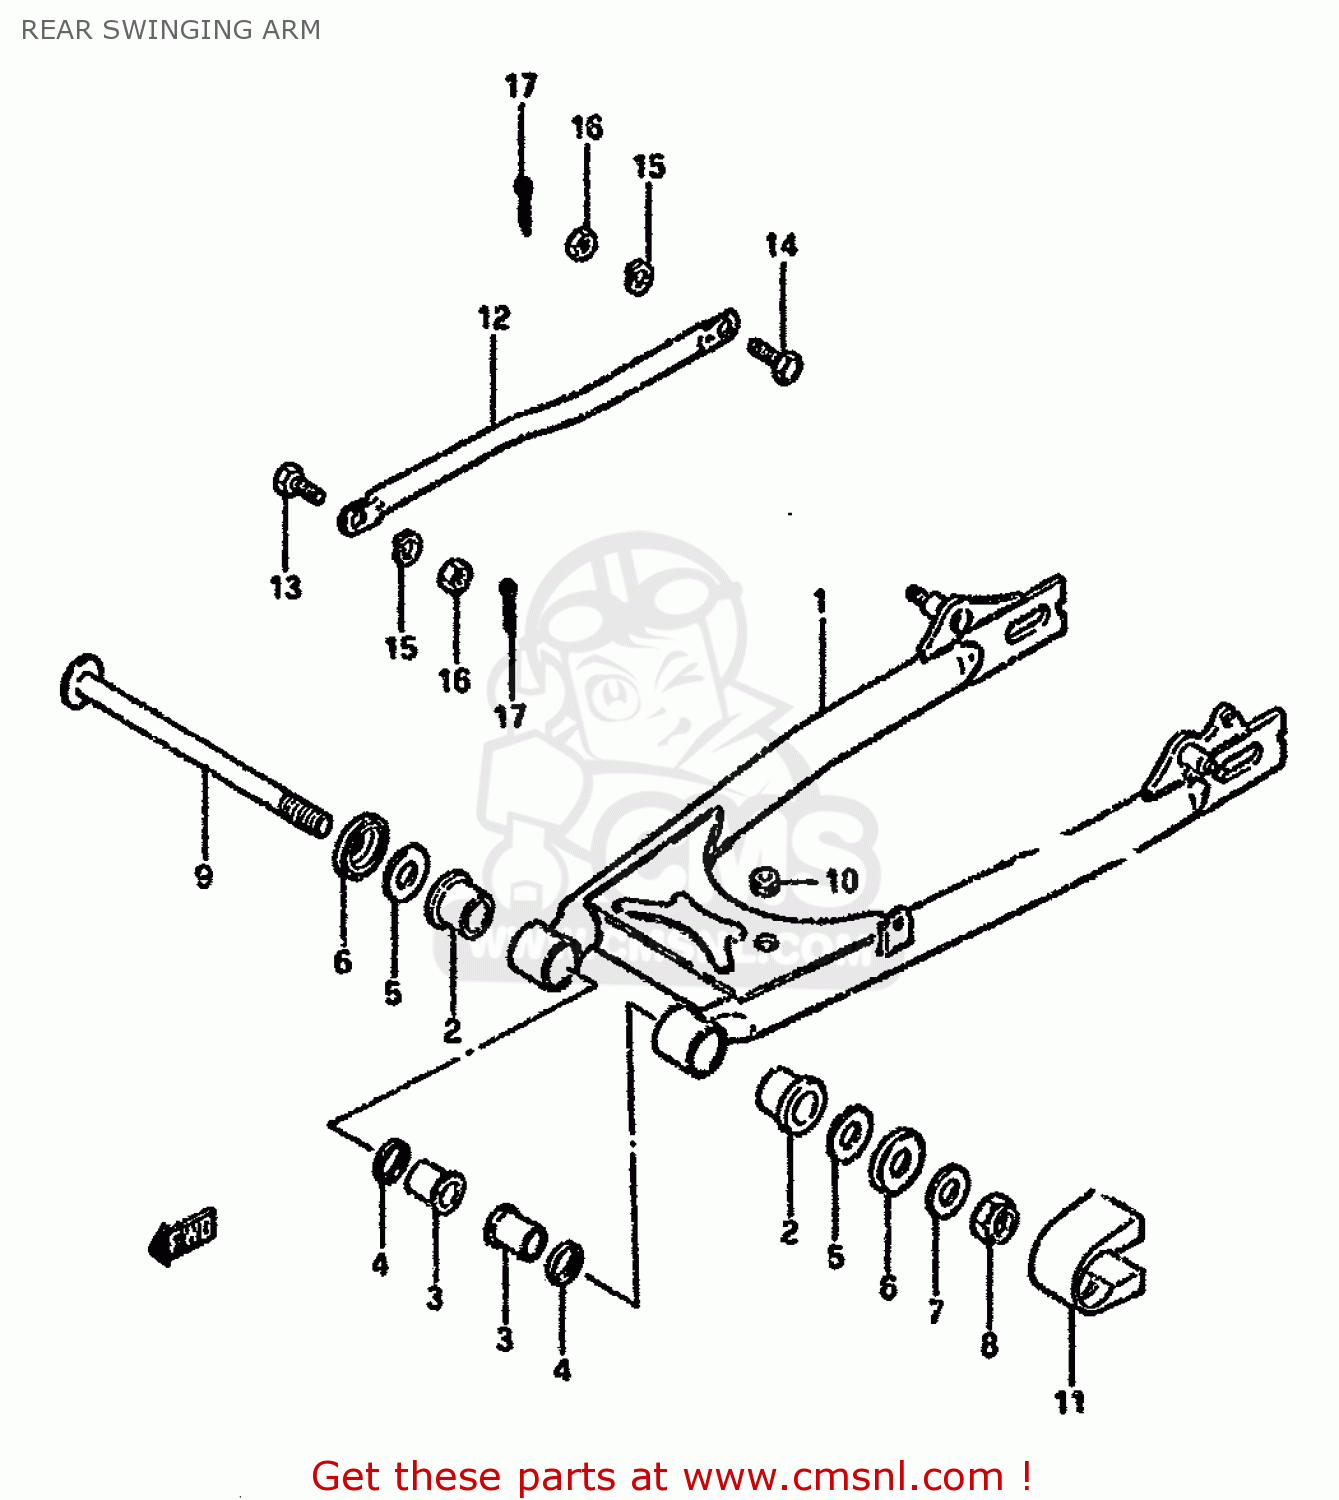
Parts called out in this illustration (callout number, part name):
1	SWINGINGARM ASSY,RR
2	BUSH,RR SWINGING ARM PIVOT
3	SPACER,RR SWGARM PIVOT
4	SEAL,OIL(20X27X5)
5	WASHER
6	CVR,RR SWGARM DUST SEAL(OD:40)
7	WASHER
8	NUT 14MM
9	SHAFT,RR SWINGINGARM PIVOT
10	CUSHION
11	BUFFER,CHAIN TOUCH DEFENSE
12	LINK,RR TORQUE
13	BOLT(8X22.5)
14	BOLT(8X26.5)
15	LOCK WASHER
16	NUT
17	PIN 20X20
